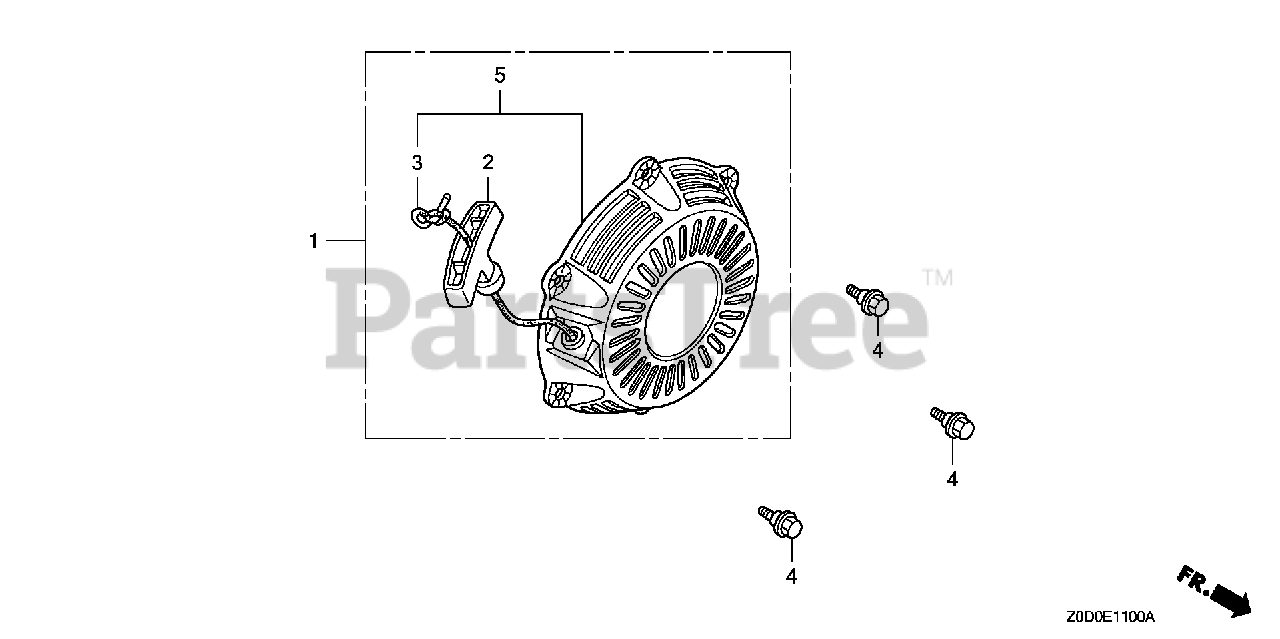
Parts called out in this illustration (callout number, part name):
1	STARTER ASSY., RECOIL *NH1* (BLACK)
1	STARTER ASSY., RECOIL *R280* (POWER RED)
2	GRIP, STARTER
3	ROPE, STARTER
4	BOLT, FLANGE (6MM)
